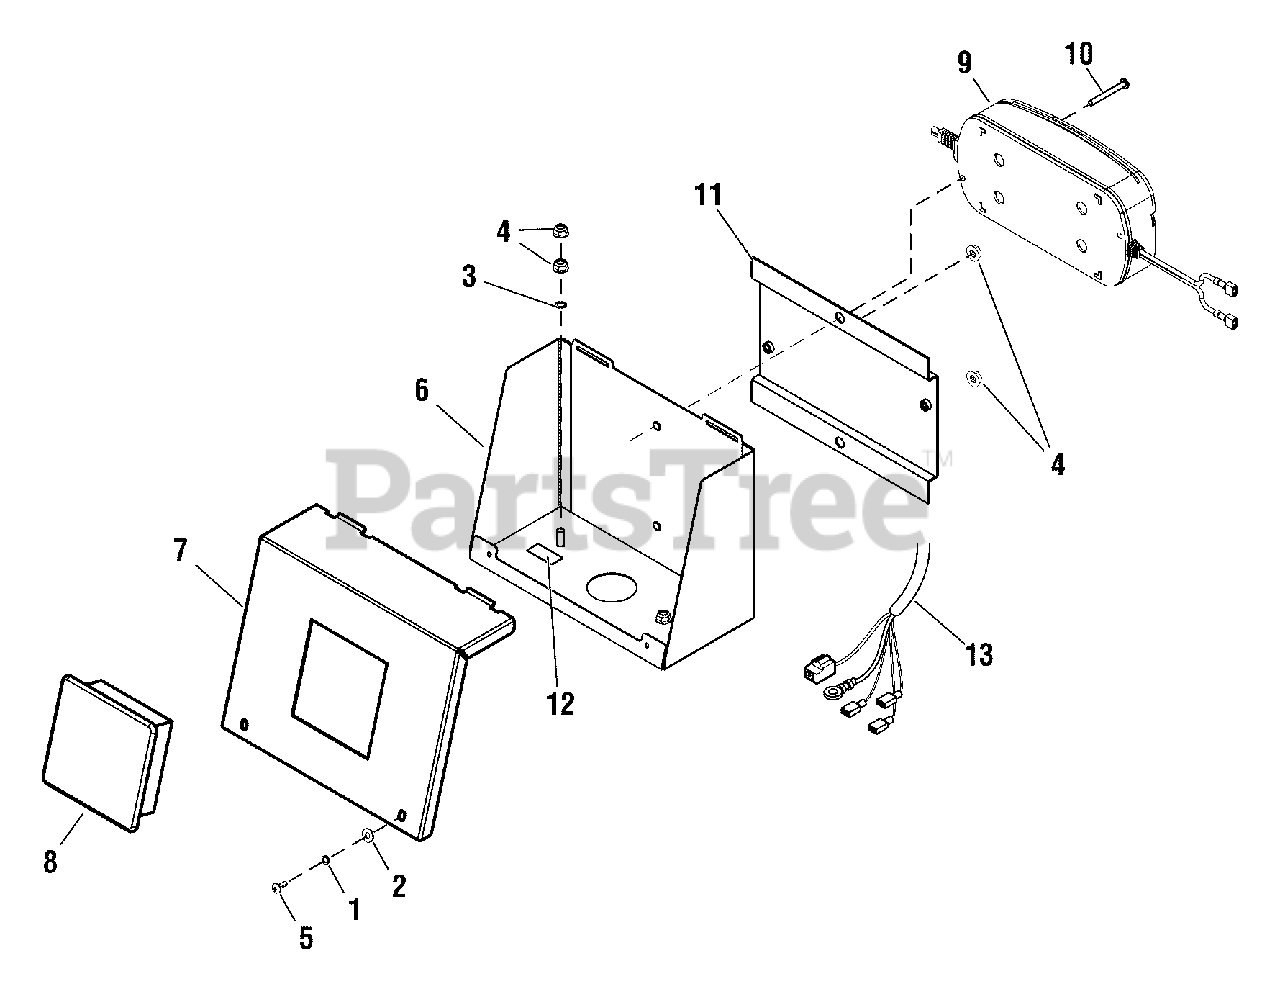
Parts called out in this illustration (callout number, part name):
1	* WASHER, Split Lock, #10
2	* WASHER, Flat, #10
3	* WASHER, External Lock, M6
4	* NUT, Flange Nylock, 1/4-20
5	* SCREW, Trilobular, 10-32 x 3/4
6	BOX-CONTROL PANEL
7	COVER-CONTROL PANEL
8	CONTROL PANEL
9	CHARGER-BATTERY
10	* SCREW, 8-32 x 1-1/2
12	DECAL
